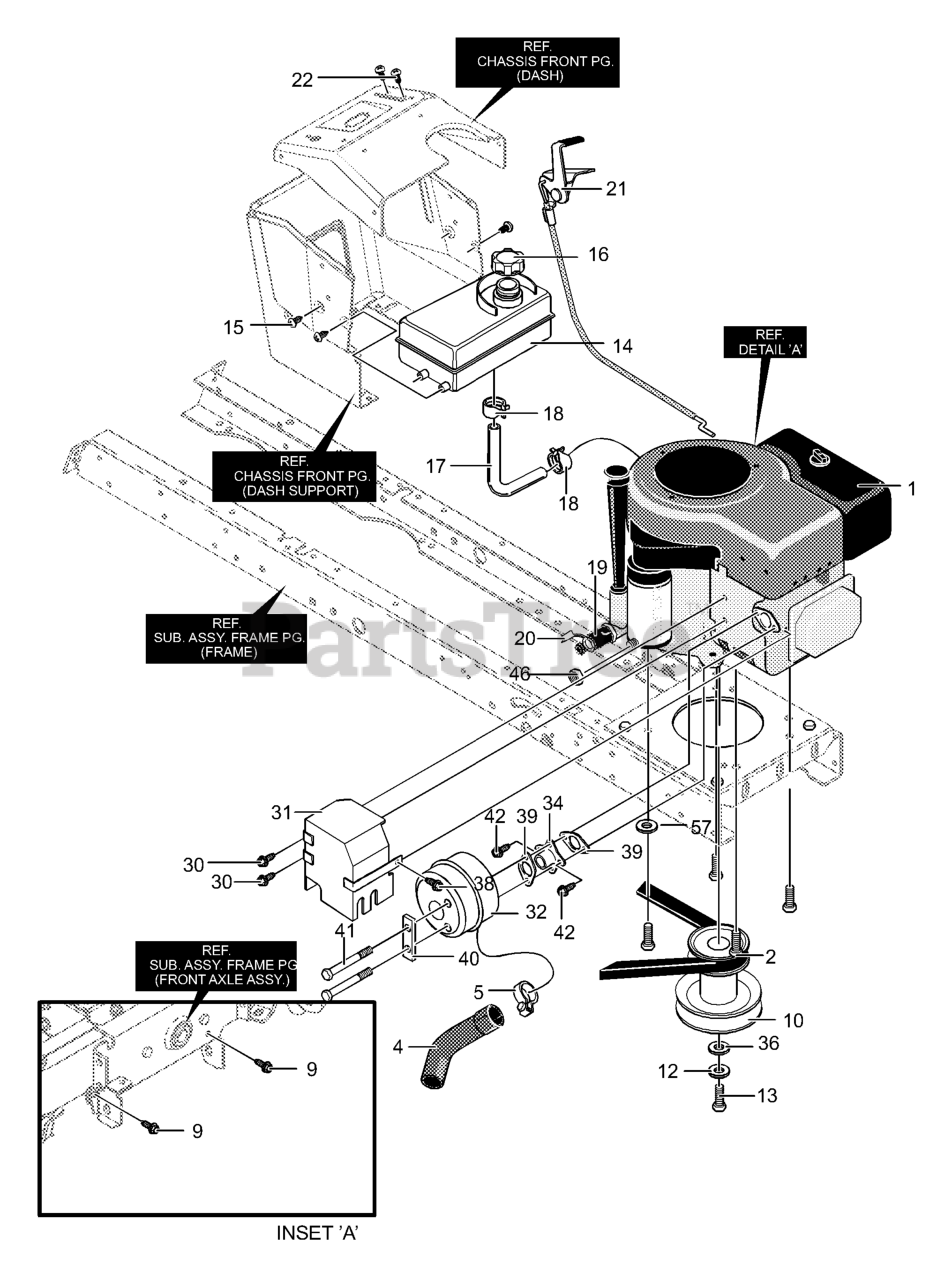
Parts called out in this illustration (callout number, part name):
1	ENG., 14.5OHVI/C W/O MUFF
2	BOLT-3/8 X 1.25
4	PIPE, EXHAUST 14.5/15.5
5	CLAMP ASSEMBLY
10	STACK PULLEY
12	WASHER
13	BOLT, 7/16-20 X 1.75
14	TANK, Fuel 1.4 Gal.
16	FUEL CAP
17	TUBING
18	CLAMP, FUEL LINE
19	OIL DRAIN VALVE ASSEMBLY
20	CAP,OIL DRAIN VALVE ASM.Y
21	THROTTLE, CONTROL
31	HEAT SHIELD ASSY
32	MUFFLER, ROUND
34	MUFFLER ADAPTER
38	SCRW
39	GASKET, Exhaust
40	BRACKET, LOCK (92378)
57	WASHER
